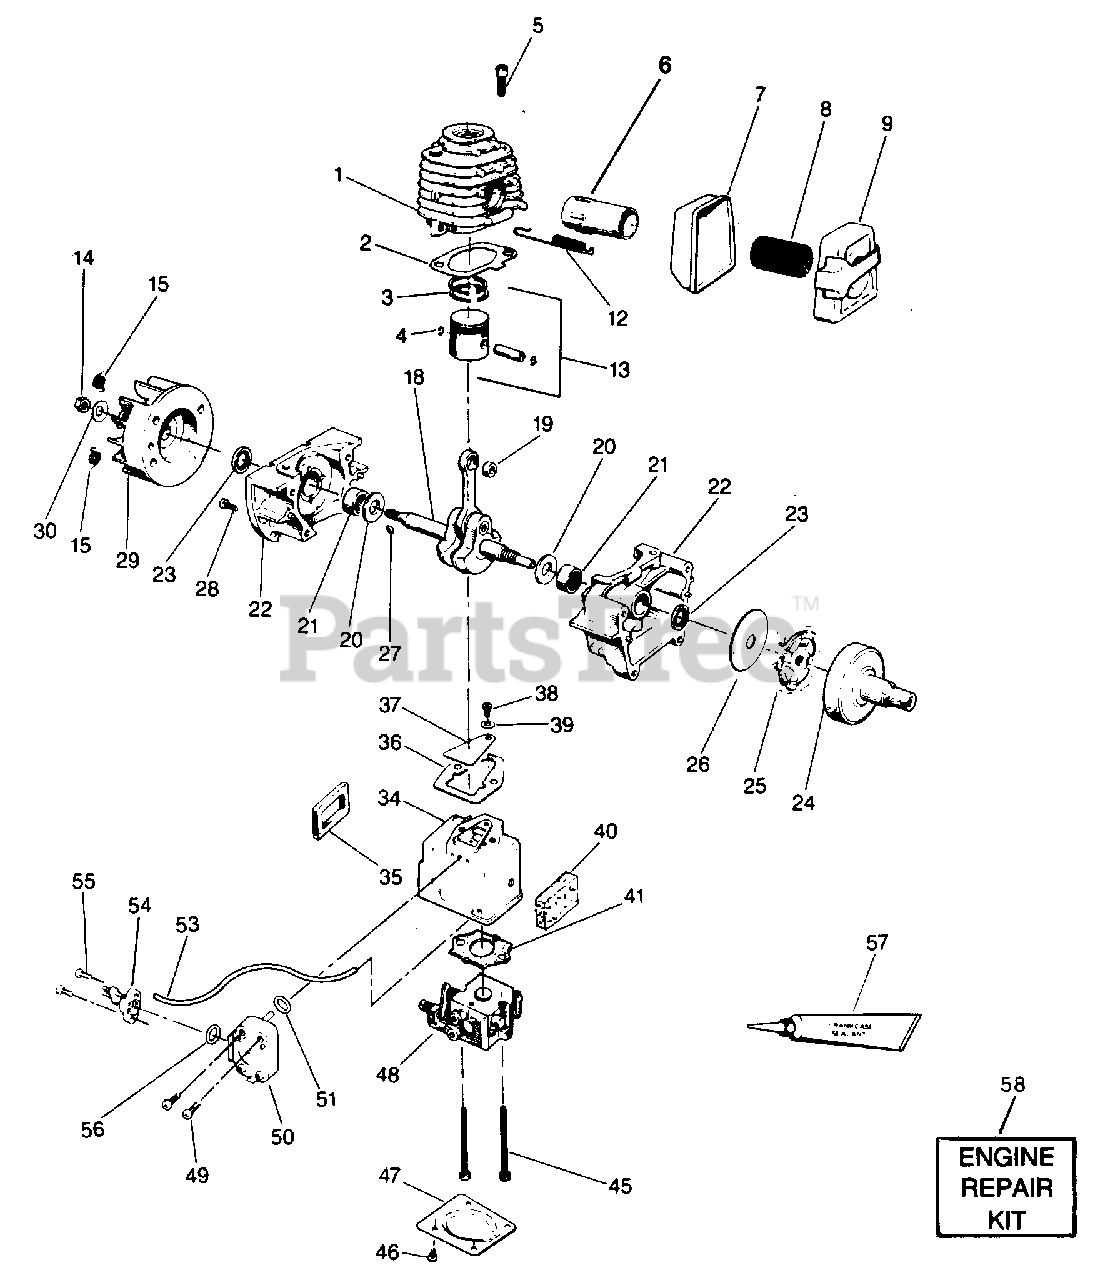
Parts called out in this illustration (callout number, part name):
1	Cylinder - See Service Ref. 2.
2	Gasket - Cylinder
3	Ring - Piston - See Service Ref. 1.
4	Retainer - Wrist Pin (PRO150 Only)
5	Screw - #1/4 - 20 x 3/4" Hex Soc. Hd. - Cylinder
6	Diffuser - Muffler
7	Body - Muffler
8	Screen - Spark Arresting
9	Cover - Muffler
12	Spring - Muffler Attachment
13	Piston Kit (Inc.3,4,Pin) See Service Ref. 1 & 2.
14	Nut - Flywheel
15	Spring - Starter Dog
18	Ass'y., Crankshaft & Rod - See Service Ref. 2
19	Bearing - Wrist Pin - See Service Ref. 2.
20	Washer - Thrust - Crankcase
21	Bearing - Crankcase
22	Crankcase Ass'y. (Inc.21, 23 & Qty. 4 of 28)
23	Seal - Crankcase
24	Drum & Coupling Assembly
25	Kit - Clutch Assembly (Incl. Clutch Washer)
26	Kit - Clutch Washer
27	Key - Flywheel
28	Screw - #10 - 24 x 5/8" Fil. Hd. Crankcase
29	Flywheel Assembly (Inc.15)
30	Washer - Flywheel
34	Ass'y. Carburetor Housing & Eyelet
35	Seal - Carburetor Case
36	Gasket-Carburetor Case to Crankcase
37	Reed Valve
38	Screw - #6 - 19 x 5/16" - Pan. Hd. - Reed Valve
39	Washer - Reed Valve Screw
40	Seal - Carb. Case (Sponge)
41	Gasket - Carburetor
45	Screw - #10 - 24 x 2-1/4" - Fil. Hd. - Carburetor
46	Screw - #8 - 18 x 9/16" - Pan. Hd. - Carburetor Case Cover
47	Cover - Carburetor Case
48	Carburetor - WA - 149 - Cable
49	Screw - #8 - 18 x 1",- Accumulator
50	Accumulator Assembly (Inc.51 & 54)
51	O-Ring (Orifice)
53	Fuel Line - Carburetor
54	Cap Assembly - Accumulator (Inc.56)
55	Screw - #8 - 16 x 9/16"
56	O-Ring (Accumulator Chamber)
57	Sealant - Crankcase (Not supplied with unit)
